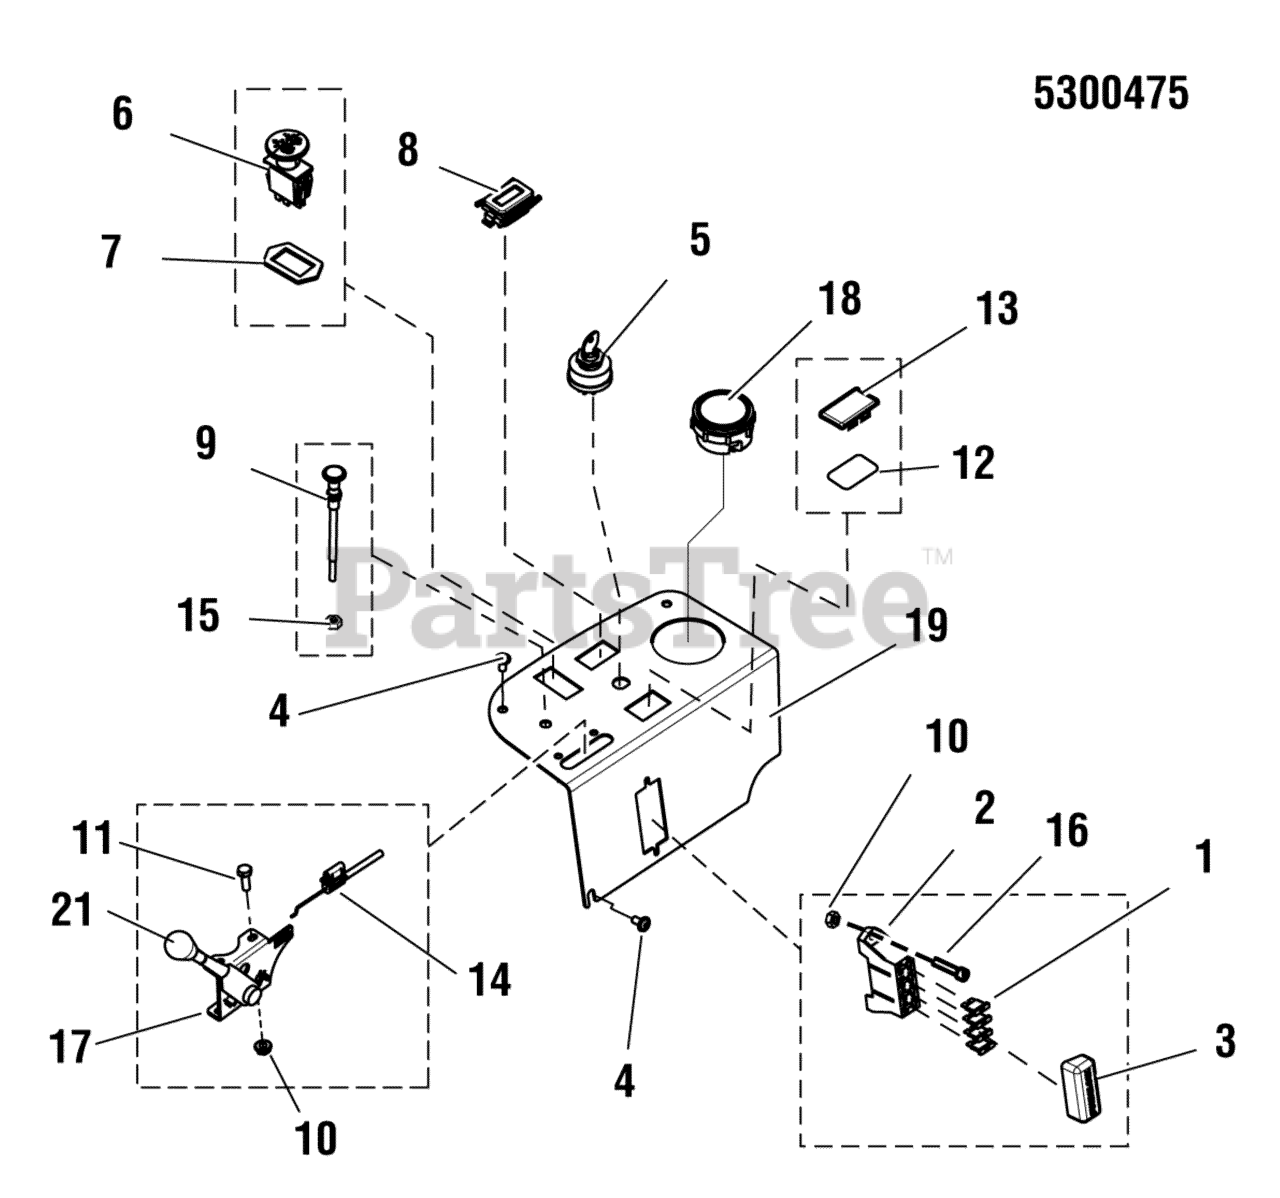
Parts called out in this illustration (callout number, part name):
1	FUSE, ATO 20 AMP
2	FUSE, BLOCK
3	COVER, VINYL FUSEBLOCK
4	SCREW, 1/4-20 X 1/2" ALLEN BH
5	SWITCH, IGNITION, 6 POST
6	SWITCH, BLADE ENGAGEMENT
7	RING, SWITCH RETAINER
8	HOUR METER
9	CABLE, CHOKE CONTROL, 47"
10	NUT, #10-24 HEN NYLON LOCK
11	SCREW, #10-24 X 3/4"
12	O-RING, 7/8" ID X 1/16"
13	PLUG, .820X1.44 HOLE, BLACK PLASTIC
14	CABLE, THROTTLE, 42"
15	NUT, 3/8 - 24 HEX
16	SCREW, #10-24 X 2" ROUND PHILLIPS
17	THROTTLE CONTROL HANDLE/KNOB
18	GUAGE, WATER TEMPERATURE
19	PANEL, CONTROL, IS2000Z LC
20	LEVER, THROTTLE CONTROL, HEAVY-DUTY
